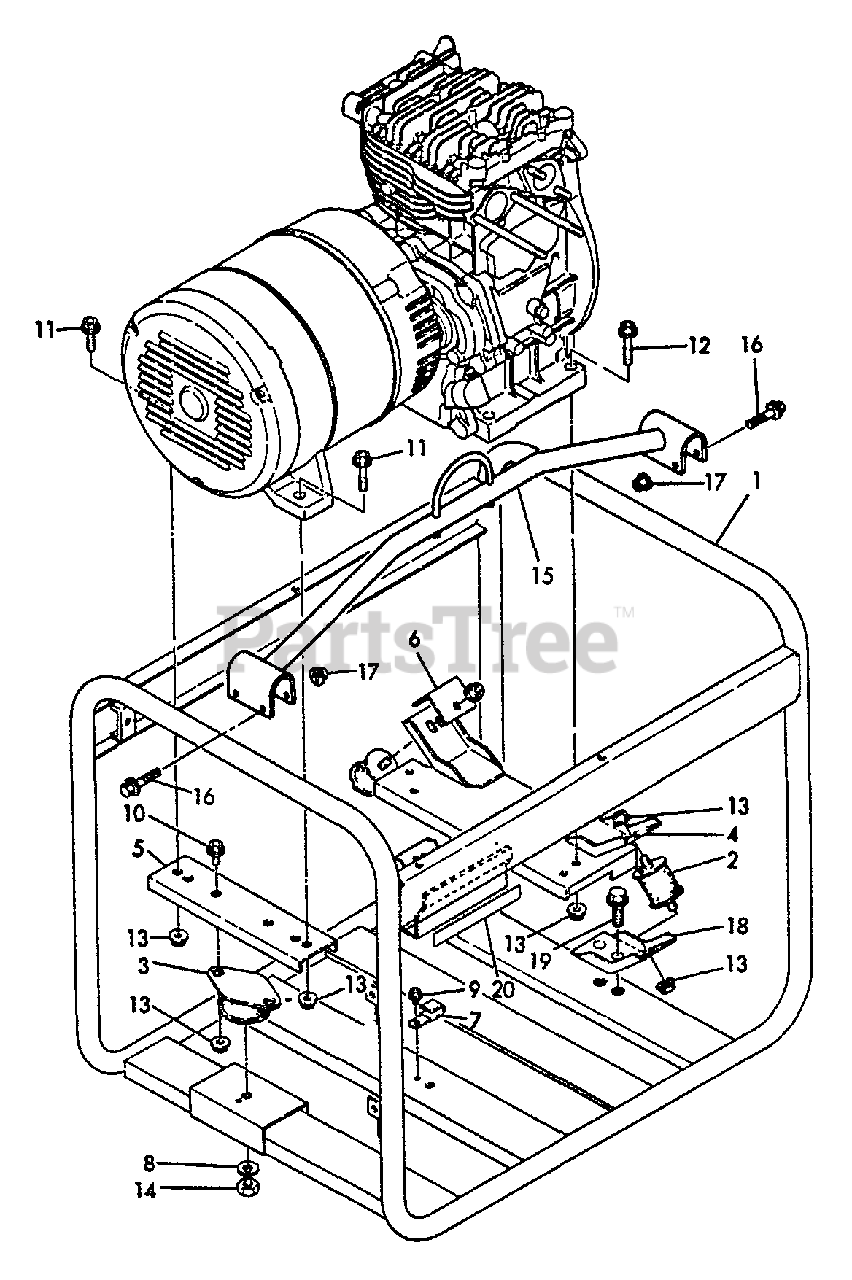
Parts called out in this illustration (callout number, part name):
1	FRAME
2	DAMPER, FRONT
3	DAMPER, REAR
4	STAY, DAMPER
5	STAY, REAR DAMPER
6	COVER, DAMPER
7	CLAMP
8	LOCKWASHER - 10
9	BOLT - 6×8 -- PLATED
10	BOLT - 8×20 -- PLATED
11	BOLT - 8×30 -- PLATED
12	BOLT - 8×38 -- PLATED
13	U-NUT M8
14	NUT - 10
16	BOLT - 6×40
17	U-NUT M6
18	DAMPER STAY, LOWER
19	BOLT - 8×16 -- PLATED
20	SHEET, FRAME
